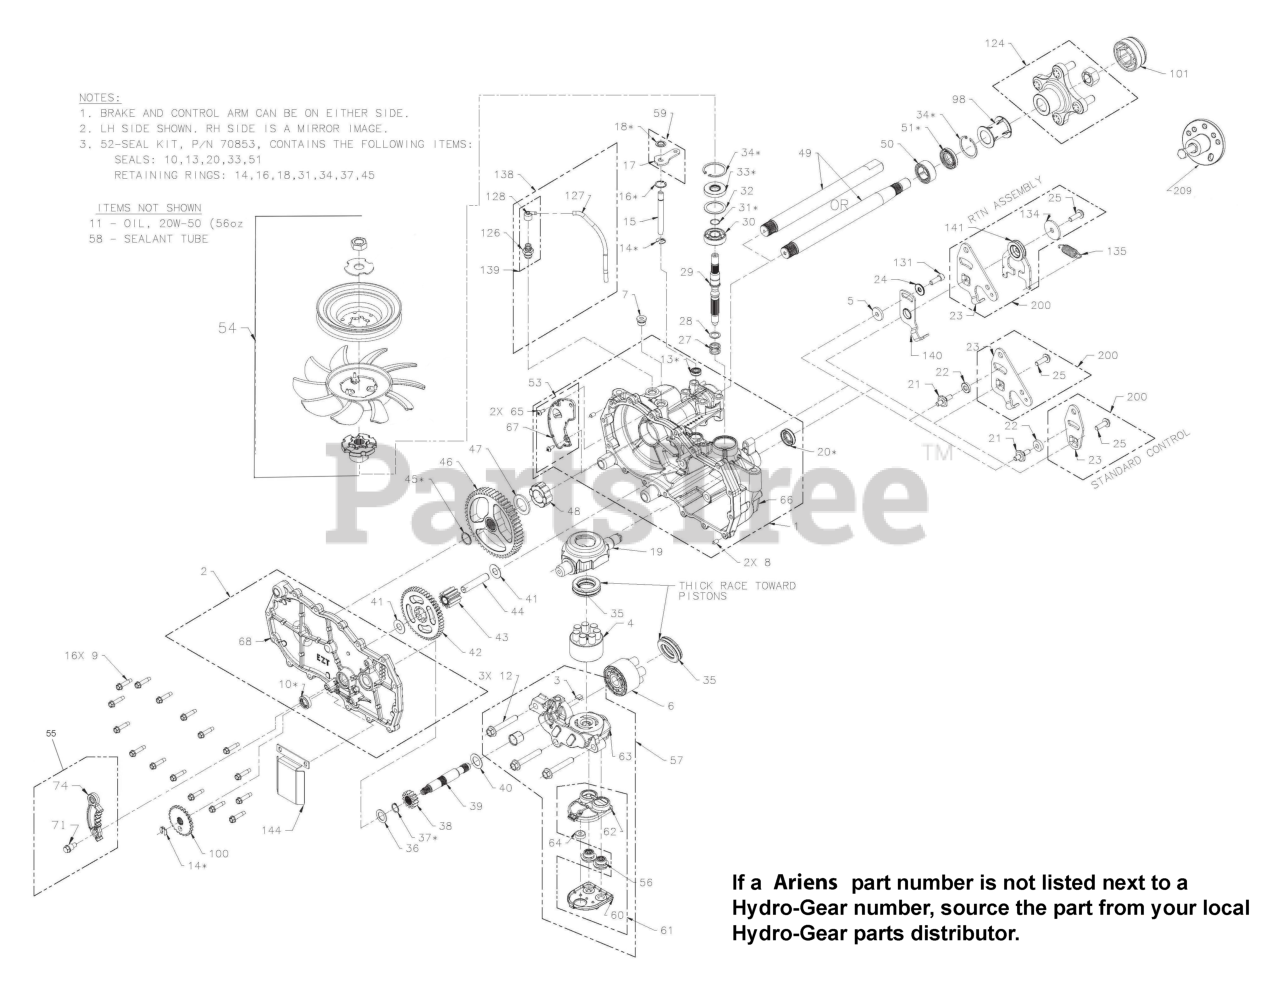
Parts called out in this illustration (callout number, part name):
1	ASSEMBLY, MAIN HOUSING-LH
2	HG (70863L)
4	ASSY, BLOCK 7 PISTON
5	SPACER
6	KIT, 10 CC BLOCK
7	PLUG, 9/1 6- 18
9	SCREW,HEX WASHER 1/4-20X1.125
10	SEAL, LIP .625 X 1.000 X .250
10	SEAL, LIP .50 X .88 X .25
13	SEAL, LIP .375 X .75 X .25
14	RING, RETAINING .375 EXT
15	ROD, BYPASS
16	RING, RETAINING .750 INT
18	RING, RETAINING .375 EXT
19	TRUNNION, SWASHPLATE
20	SEAL, LIP 18 X 32 X 7
24	WASHER
27	SPRING. BLOCK
28	WASHER. THRUST .59 X .79 X .04
29	SHAFT, INPUT
30	BRG, BALL 17X40X12
31	RING, RETAINING WIRE .561 ID
32	WASHER 1.23X1.56X.04
33	BATTERY, GROUP 26, 540CCA
34	BATTERY, GROUP 26, 540CCA
35	BEARING. THRUST 30 X 52 X 13
36	WASHER .63X1.0X.05
37	RING, RET 62 EXT
38	GEAR, 13T PINNION
39	SHAFT, MOTOR
40	WASHER .71 X 1.16 X .04
41	WASHER .5X1.0X.032
42	GEAR, 10T/48T
43	GEAR, 10T JACKSHAFT
44	JACK SHAFT (PIN)
45	RING, SPIRAL RETAINING
46	GEAR, 52T BULL
47	WASHER, I.018 X I.57 X .I05
48	SLEEVE BEARING
49	SHAFT, AXLE
50	BEARING, SLEEVE, I.00 X I.57 X .62
51	SEAL, LIP 1.00 X 1.57 X .25
51	SEAL, LIP .375 X .75 X .25
52	KIT, SEALS AND RETAINING
53	KIT, EXPANSION PLATE LH
54	KIT-FAN & PULLEY-6"
55	BRAKE ARM, EZT #70865
57	KIT, CENTER SECTION, W/FILTER - LH
58	SEALANT TUBE 10.1OZ.
59	KIT, BYPASS ARM
61	KIT, FILTER
98	TUBE, AXLE
100	DISC, COG BRAKE
101	CAP, AXLE
124	KIT, HUB 1/2-20
131	KIT, RTN SCREWS
135	SPRING, EXTENSION
138	KIT, BREATHER ASSEMBLY
139	KIT, BREATHER ASSEMBLY
140	ARM, NEUTRAL LEFT
200	KIT, RTN, BIDIRECTIONAL
209	HUB PULLER 4 BLT HYDGEAR 71459
